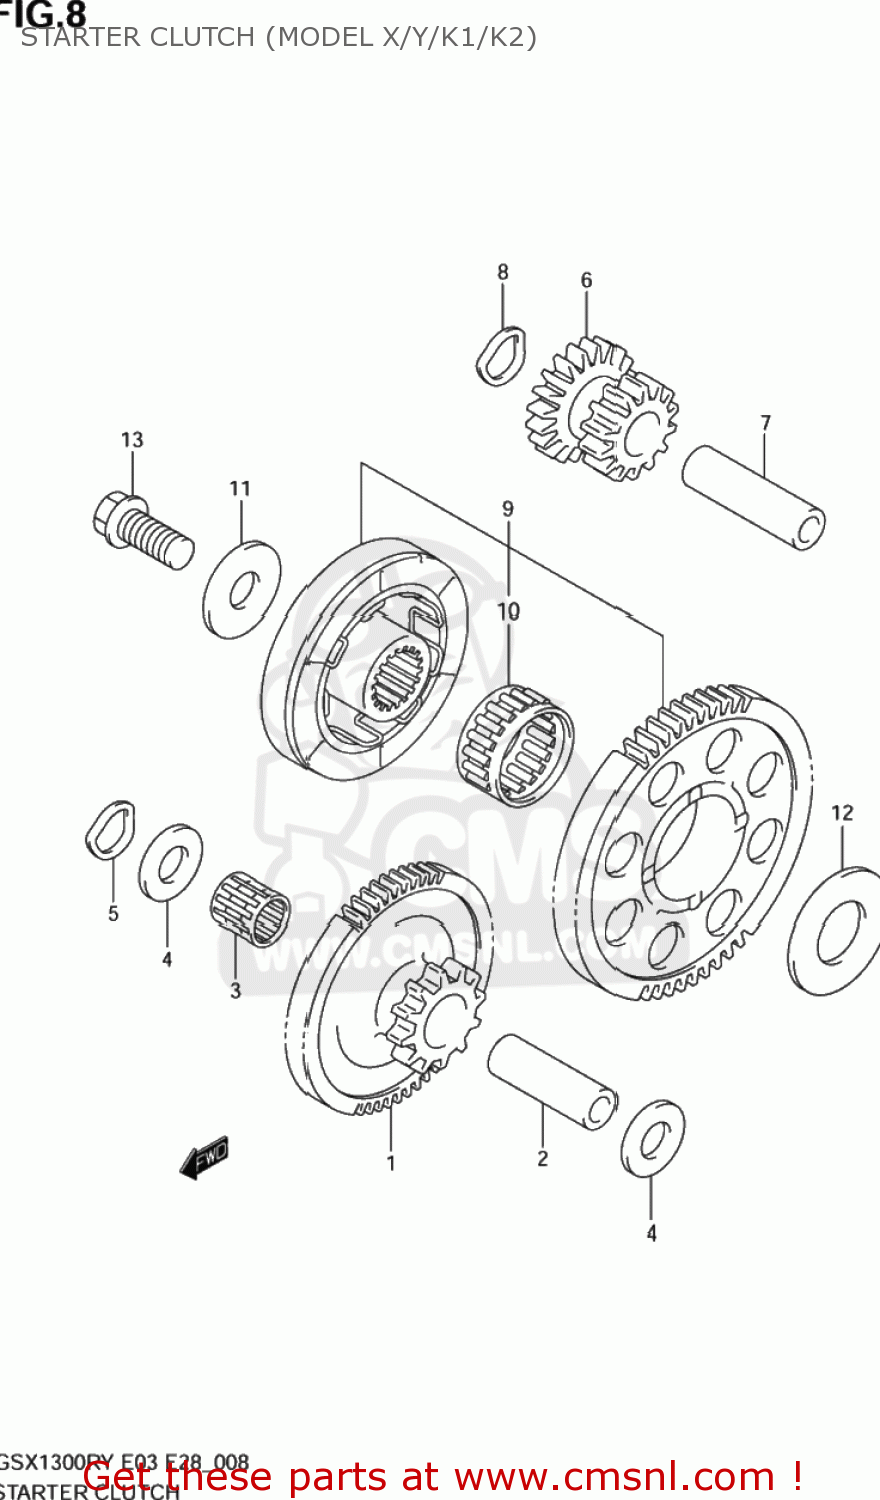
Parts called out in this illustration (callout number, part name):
1	GEAR,STARTER IDLE NO.1
2	PIN,PISTON
3	BEARING(12X16X16)
4	WASHER
5	WASHER
6	GEAR,STARTER IDLE NO.2
7	PIN ,PISTON
8	WASHER
9	CLUTCH SET,STARTER
10	BEARING(28X34X16.8)
11	WASHER
12	WASHER
13	BOLT(10X23)
